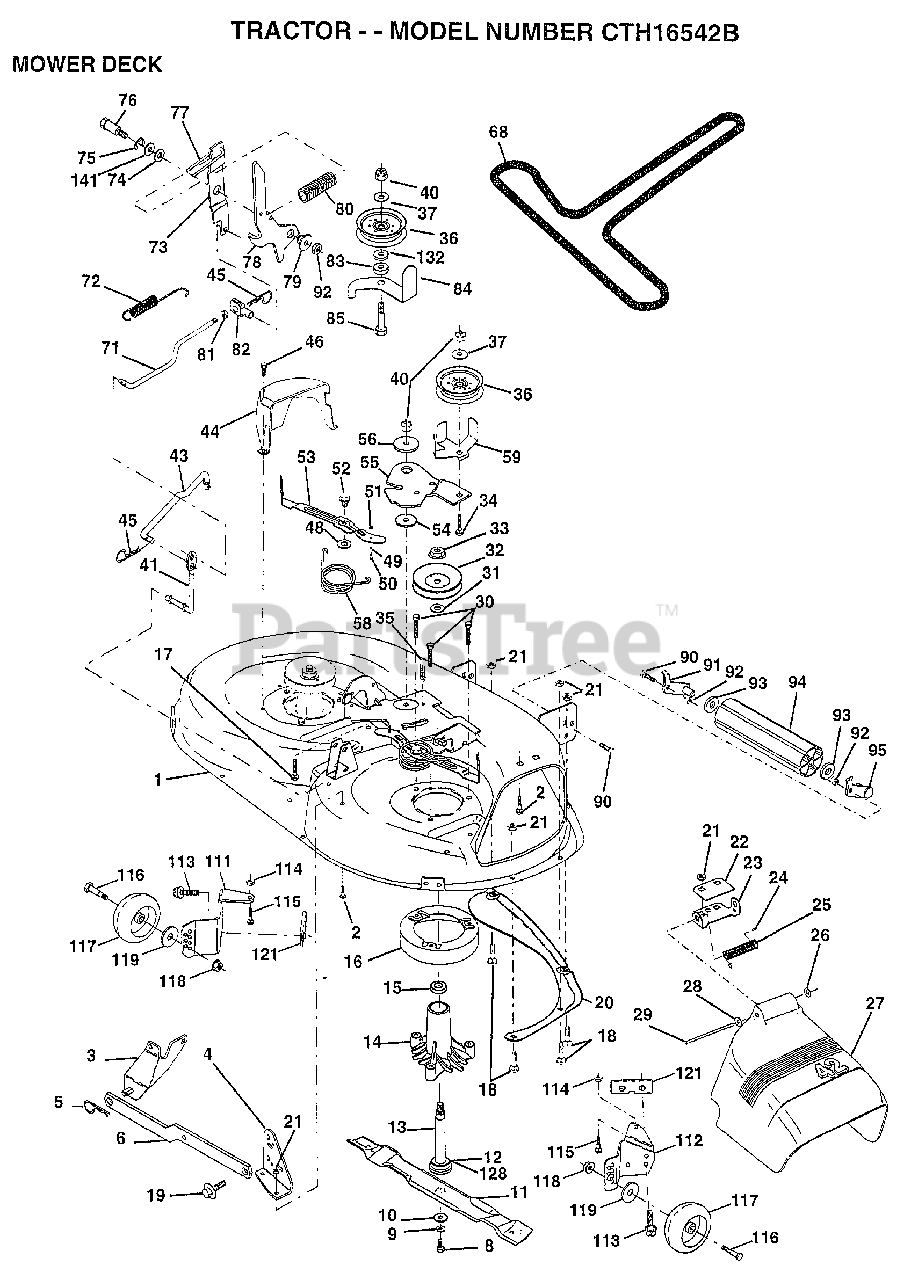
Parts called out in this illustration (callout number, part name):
1	"HOUSING ASSY.42"""
2	BOLT
3	BRKT ASM SWAY BAR
4	BRKT DECK SW BAR
8	BLADE BOLT
10	WASHER.HARD.BLADE
11	"BLADE.42"" HIPERF"
12	BEARING.BALL
14	HSG ASM MANDREL
15	BEARING
16	STRIPPER RND MWR
17	BOLT RDHD 3/8-16
18	BOLT
19	BOLT SHD 5/16-18
20	BAFFLE VORTEX 42
22	STIFFENER BRKT
23	DEFLECTOR BRKT
25	SPRING TORSION
27	DEFLECTOR.SHIELD
28	WASHER
29	HINGE ROD
30	"SCREW-THD ROLL,WA"
31	WASHER
32	PULLEY.MANDREL.42
34	BOLT
35	XMAS TREE FASTNER
36	FLAT IDLER PULLEY
37	WASHER
41	PIVOT ROD
43	ROD CLUTCH W/NIBS
44	GUARD MAND LH BLK
46	SCREW.1/4-20X5/8
48	HARD SMALL WASHER
49	ROLLER ASM-CAM
50	SHOULDER BOLT
51	LOCKNUT
52	BOLT.SHLD.5/16-18
53	BRAKE PAD ARM ASM
54	HARDENED WASHER
55	ARM-IDLER
56	SPACER RETAINER
58	SPRING TORSN BRAK
59	GUARD IDLER TUV
68	BELT.V.T-PATH
71	ROD CLUTCH 38/42
72	SPRING.EXT.RETURN
73	CLUTCH ARM SECOND
74	WASHER
75	RING
76	SHOULDER BOLT
77	SPRING KEEPER
78	ARM CLUTCH PRIMARY
79	BUSHING
80	SPRING.CLUTCH.MWR
81	NUT
82	TRUNION ADJ
83	WASHER
84	"KEEPER-BELT,FIXED"
85	BOLT
90	BOLT
92	NUT
93	WASHER
111	BRACKET.GWHL.LH.
112	BRACKET.GWHL.RH.
113	SCREW
116	BOLT.SHOULDER
117	WHEEL.GUAGE.MED.
118	LOCKNUT
119	WASHER
121	BRACKET.EXTRD.GWL
128	WASHER.FELT.
132	WASHER GT
141	WASHER .T
